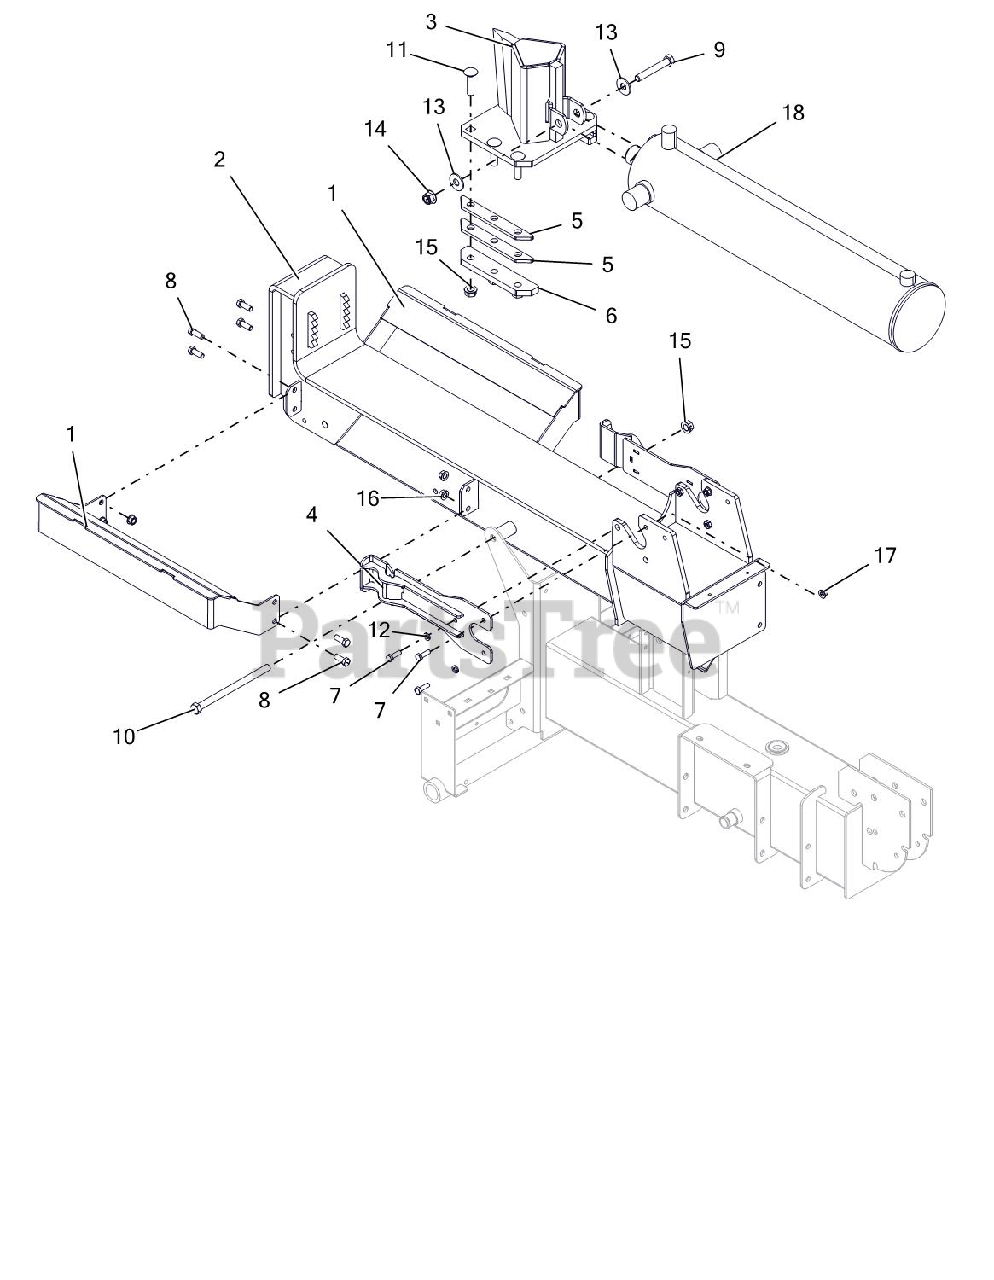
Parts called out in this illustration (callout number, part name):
1	WLDMT, CRADLE, LOG SPLITTER
2	WLDMT, BEAM - 27/34T SPLITTER
3	WMT, WEDGE - SPLITTER
4	WLDMT, PLATE - STRIPPER
5	SPACER, WEDGE
6	RETAINER,WEDGE
7	@BLT-HEX .31-18X1.00 GR5 YWZC
8	@BLT-HEX .38-16X1.00 GR5 YWZC
9	@BLT-HEX .50-13X3.25 GR5 YWZC
10	@BLT-HEX .50-13X7.50 GR5 YWZC
11	BLT-RDHDSQNKFTH.50-13X2 G8YWZC
12	WSHR-LK .312X.097 HVY YWZC
13	@WSHR-FL-STL.563X1.38X.109YWZC
14	@NUT-LK-NYL-FLG .50-13 YWZC
15	NUT-LK-CTR-FLG .50-13 YWZC
16	@NUT-LK-TOP-FLG .38-16 YWZC
17	@NUT-LK-TOP-FLG .31-18 YWZC
18	CYLINDER, 5' W/DECALS
